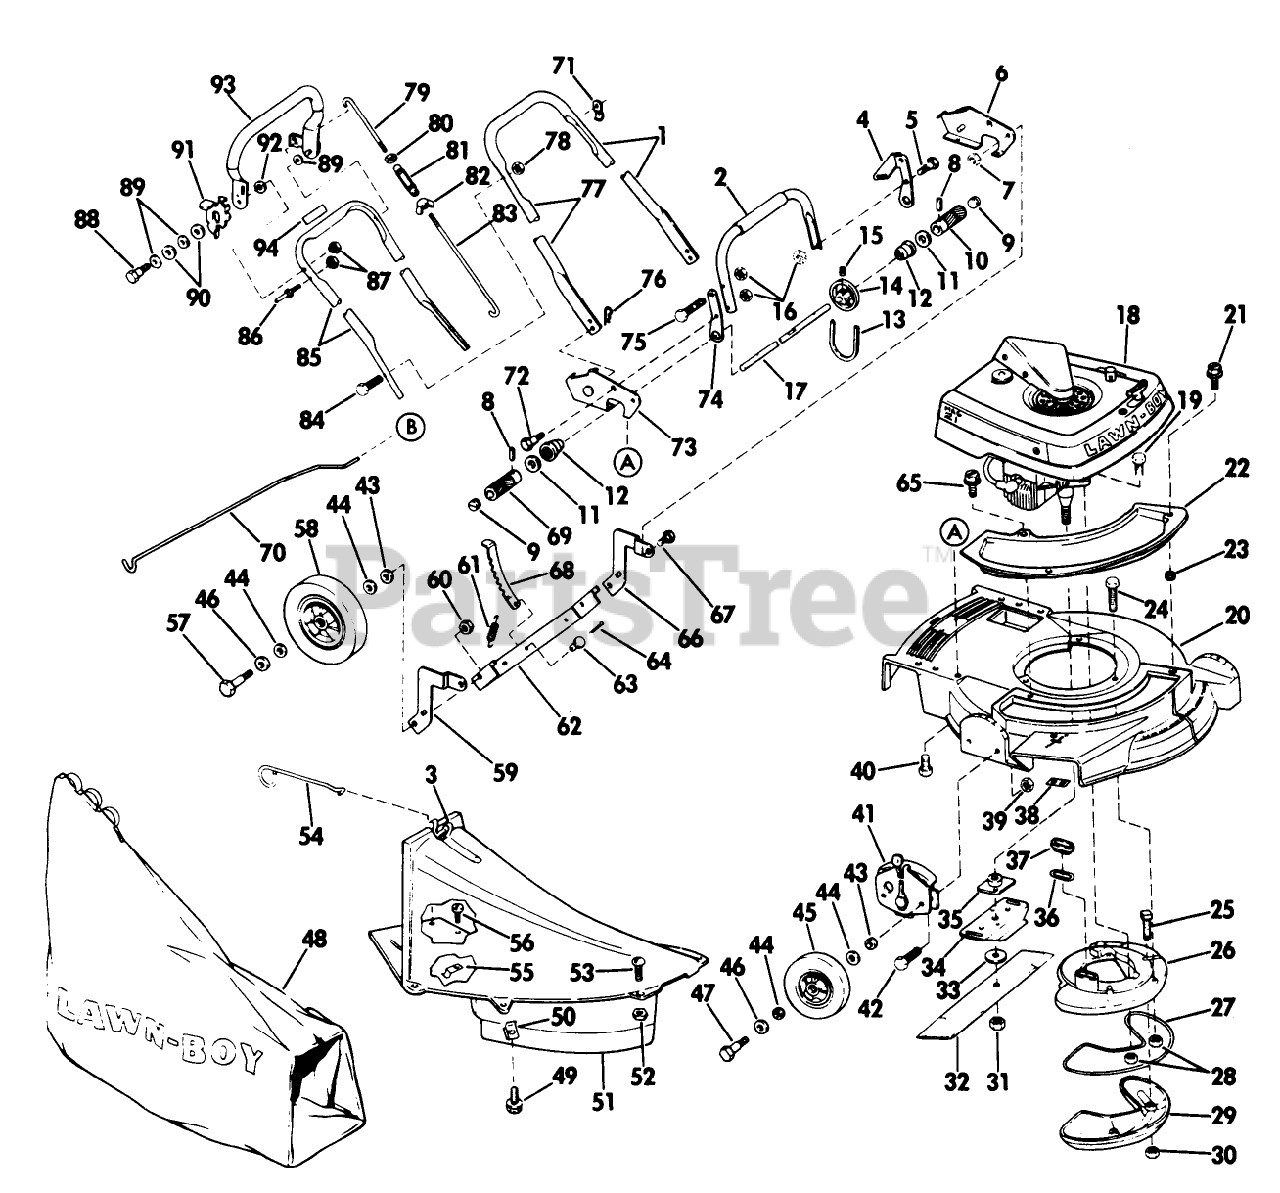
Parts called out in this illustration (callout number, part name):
1	Roller Cover Decal Assembly
7	NUT
9	GREASE PLUG
10	LEFT ROLLER
14	WASHER WROUGHT
15	Spacer-Wheel-Red
17	Roller Link Assembly-Right
21	SCREW SEMS TRM HEX HD
24	SCREW
28	NUT
30	LOCKNUT E
31	NUT-BLADE
33	WASHER
35	PLATE AND COLLAR ASM
36	GASKET S
37	SLEEVE
39	NUT
43	WASHER WROUGHT
44	WASHER
46	SPACER
47	BOLT WHEEL
48	89802 LB WHOLE GOODS
49	SCREW
50	SPEED NUT ARDEN
51	Skirt Assembly
52	NUT S
57	BOLT
60	LOCKNUT
61	SPRING N.A.S
67	BOLT-SHOULDER
70	ROD & CLIP
72	BOLT PIONEER
75	SCREW
76	HAIR PIN
84	SCREW
88	BOLT PIONEER
89	WASHER M
